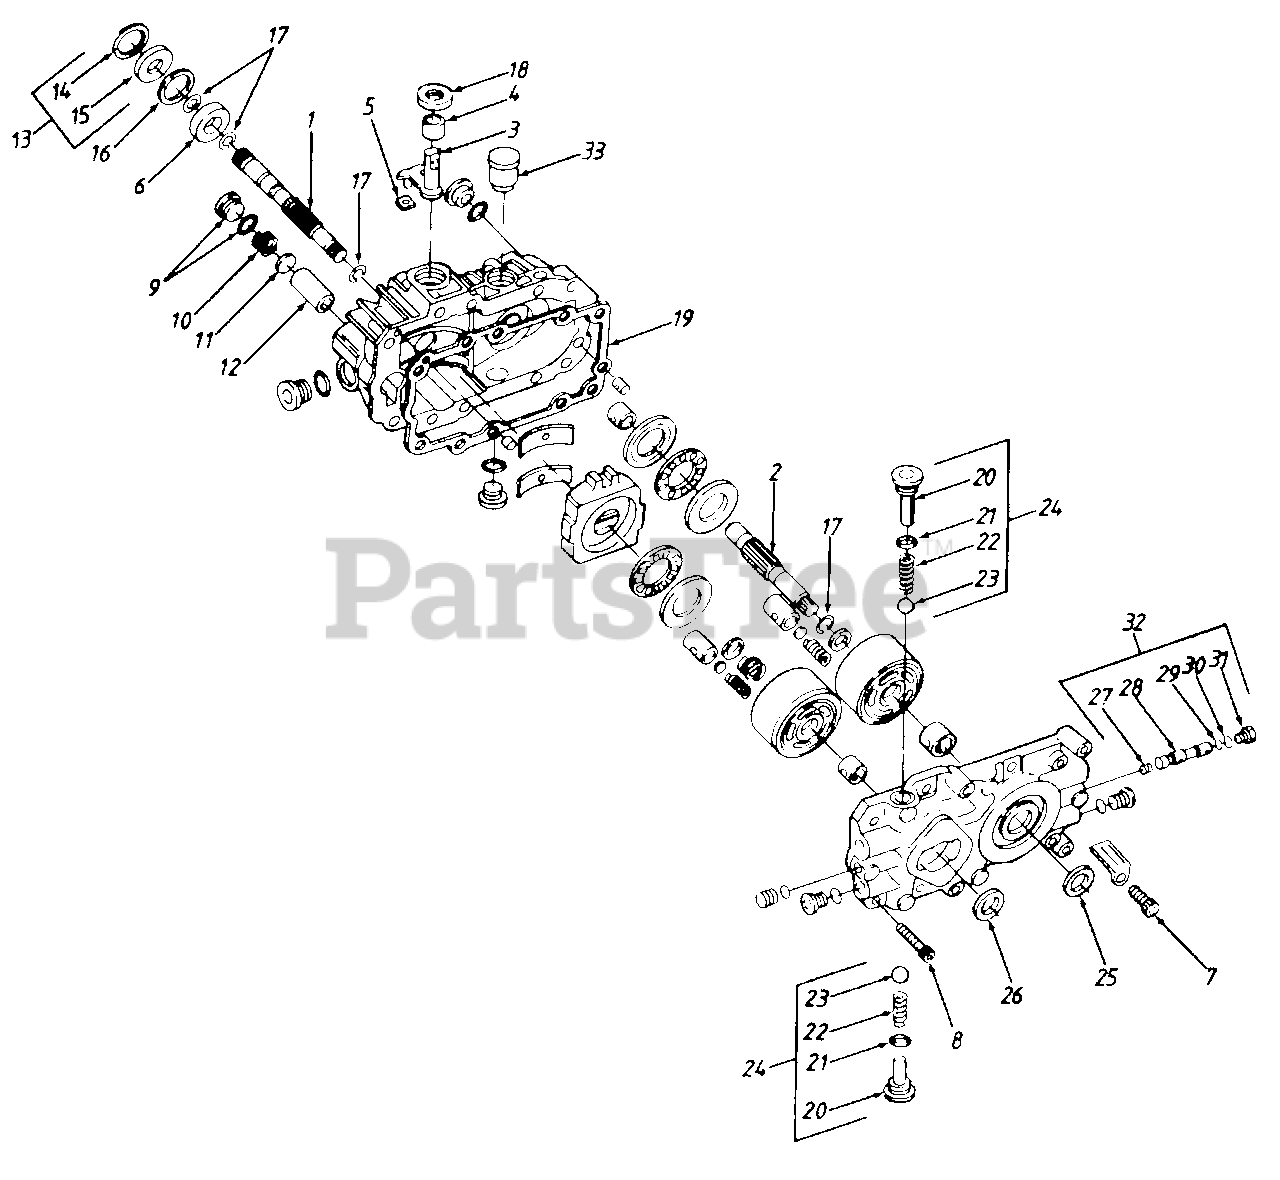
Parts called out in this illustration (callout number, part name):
1	Shaft-Pump
3	Arm, Trunnion
4	Bearing, Journal
5	Guide, Slot
6	Bearing, Ball
7	Screw, Socket Head
8	Screw, Socket Head
9	Plug
10	Spring, Filter
11	Washer, Filter
12	Filter
13	Kit, Seal
14	Ring, Retaining
15	Seal, Lip
16	Spacer
17	Ring, Retaining
18	Seal, Lip
19	Gasket
21	O-Ring
22	Spring
24	Kit, Check Valve
25	Seal, Lip
26	Seal, Lip
27	Spring
29	O-Ring
30	O-Ring
32	Kit, Bypass Valve
33	Reservoir
